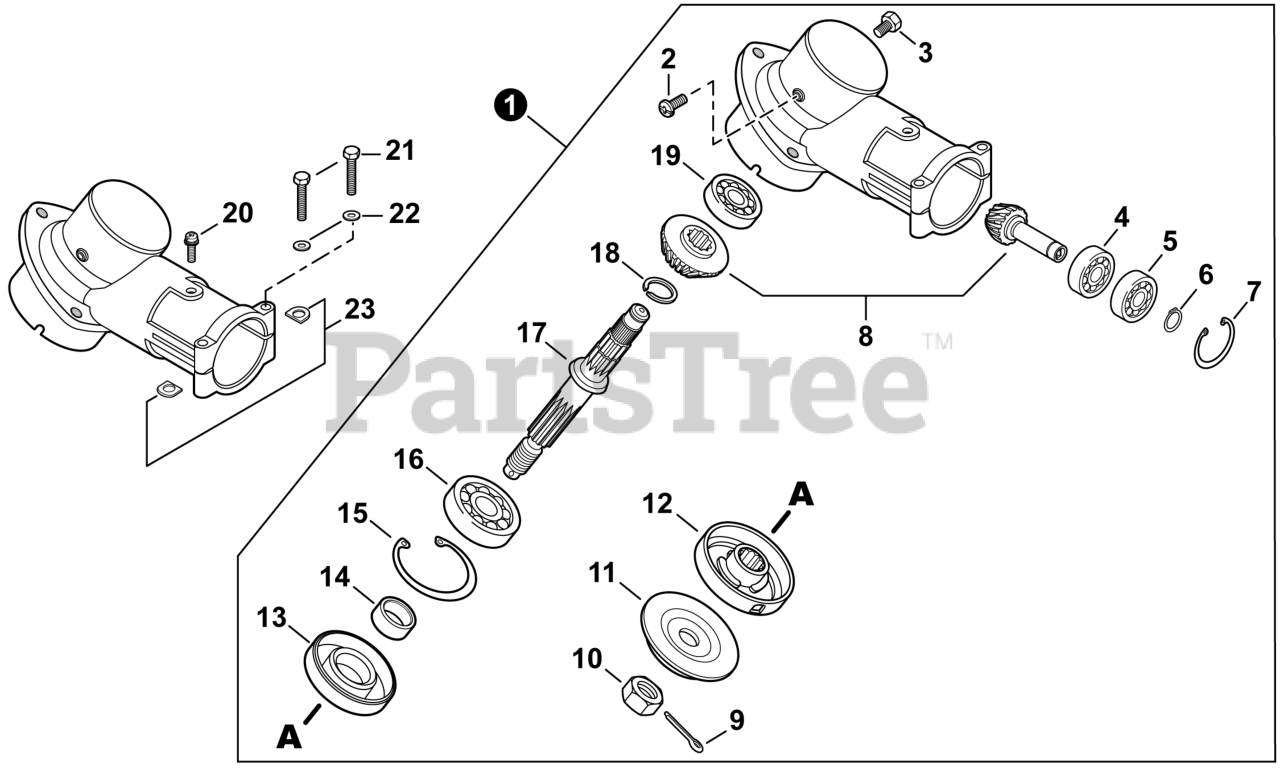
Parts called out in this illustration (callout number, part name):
1	GEAR CASE ASSY
2	SCREW 4x6
3	BOLT M8x8
4	BEARING, BALL 6001
5	BEARING, BALL 6001
6	RING, SNAP 12
7	RING, SNAP 28
8	GEAR SET
9	PIN, COTTER 2x22
11	PLATE, ADAPTOR - LOWER
12	PLATE, ADAPTOR - UPPER
13	SEAL, OIL 22
14	SPACER 11.8x15x9
15	RING, SNAP 32
16	BEARING, BALL 6201
17	SHAFT, GEAR
18	RING, SNAP 12
19	BEARING, BALL 6000
20	SCREW 5x10
21	BOLT 5x40
22	WASHER, FLAT 5.5x10x0.8
23	D-WASHER
